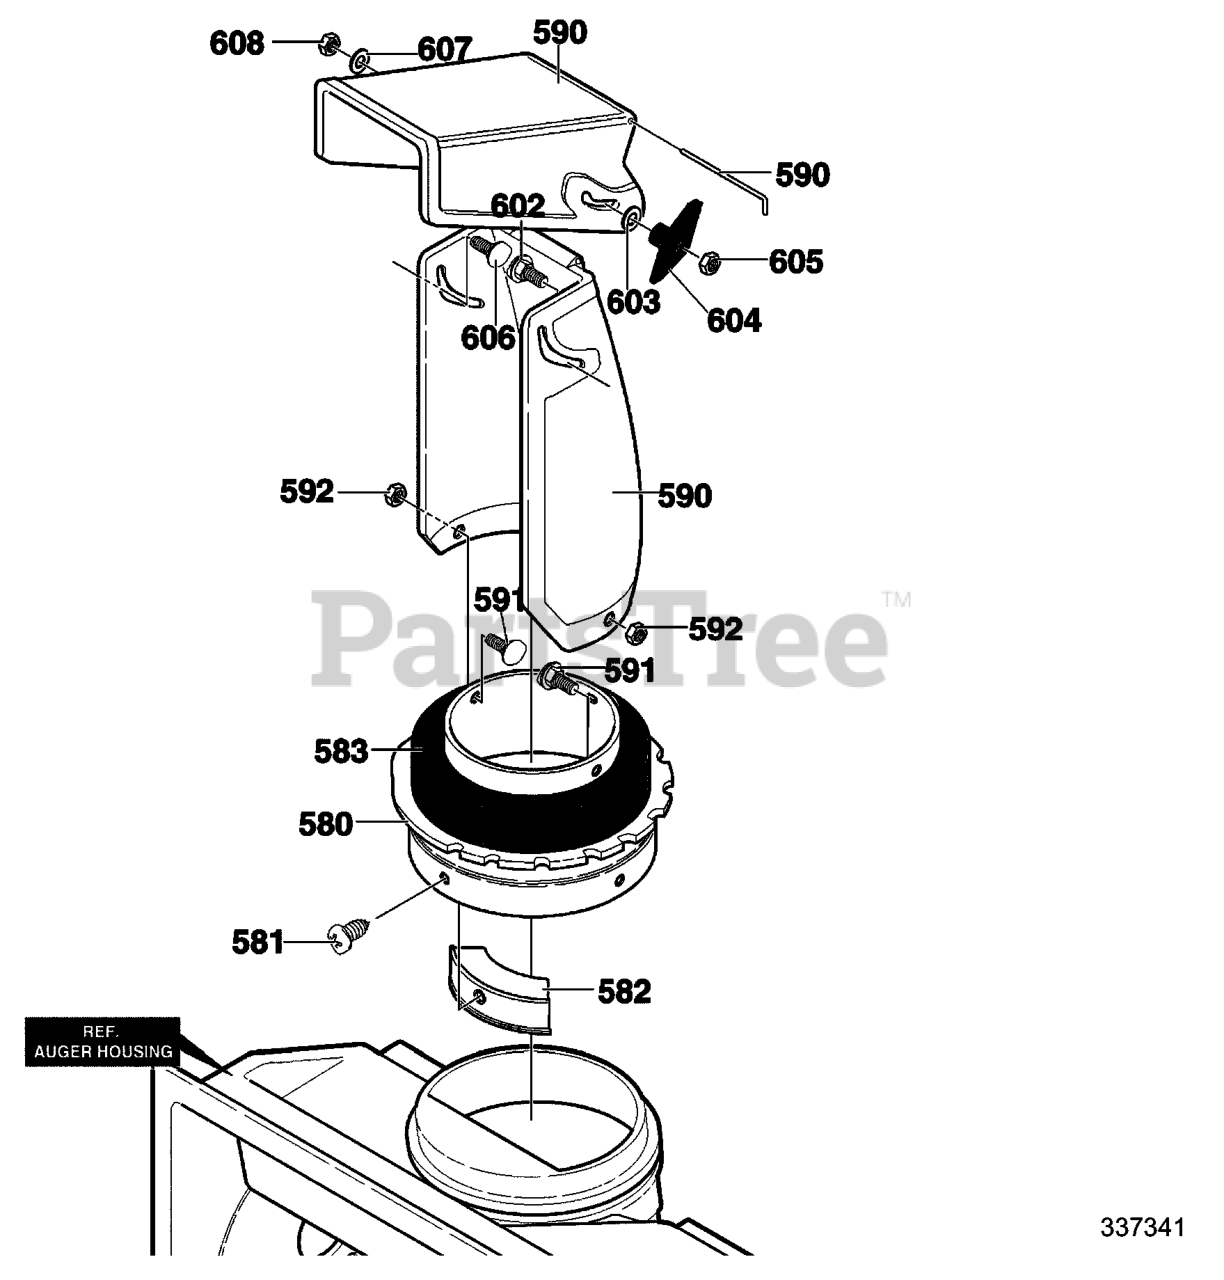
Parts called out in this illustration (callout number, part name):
580	RING, CHUTE
581	SCREW, #10X.50
582	GUIDE, CHUTE
583	DONUT FOAM
590	CHUTE ASSY.
591	SCREW 1/4-20X.50
592	NUT, 1/4-20
602	BOLT, 5/16-18X1.25 CARR.
603	WASHER, FLAT
604	KNOB, T
605	NUT, 5/16-18 HEX
606	SCREW, 5/16-18 x 0.75
607	WASHER, FLAT .349X.69X.066
608	NUT, 5/16-18
